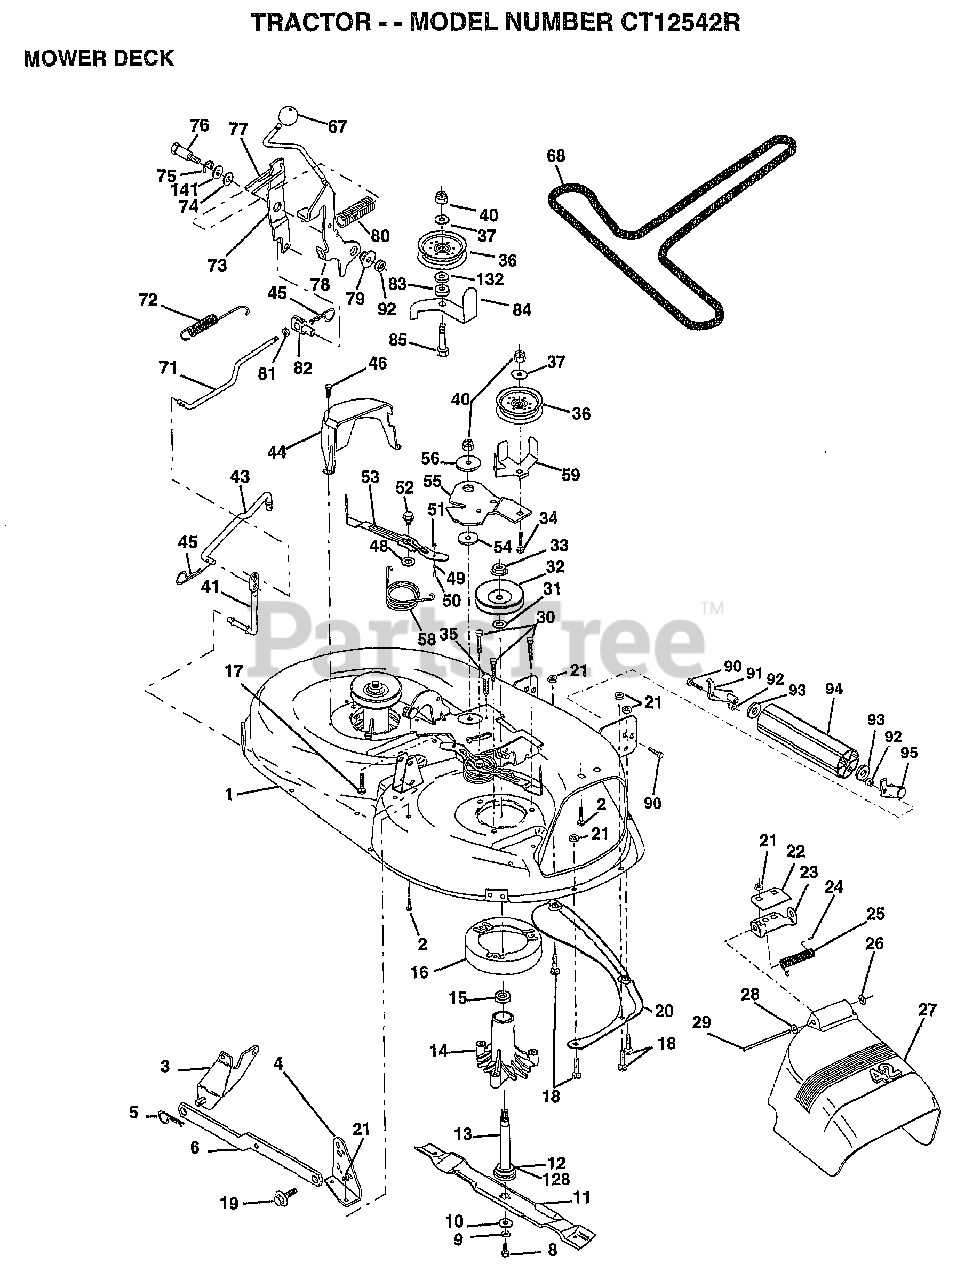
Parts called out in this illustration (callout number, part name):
1	WIRE ASM W.SPRING
2	"SHAFT ASM LIFT,RH"
3	PIN-GROOVE LT
5	WASHER
6	NYLON BEARING
7	GRIP
15	LINK.FRONT
16	NUT
17	TRUNION
18	NUT LTV
19	ARM SUSP REAR
20	RETAINER SPRING
31	BEARING PVT LH
32	NUT.CROWNLOCK.3/8
